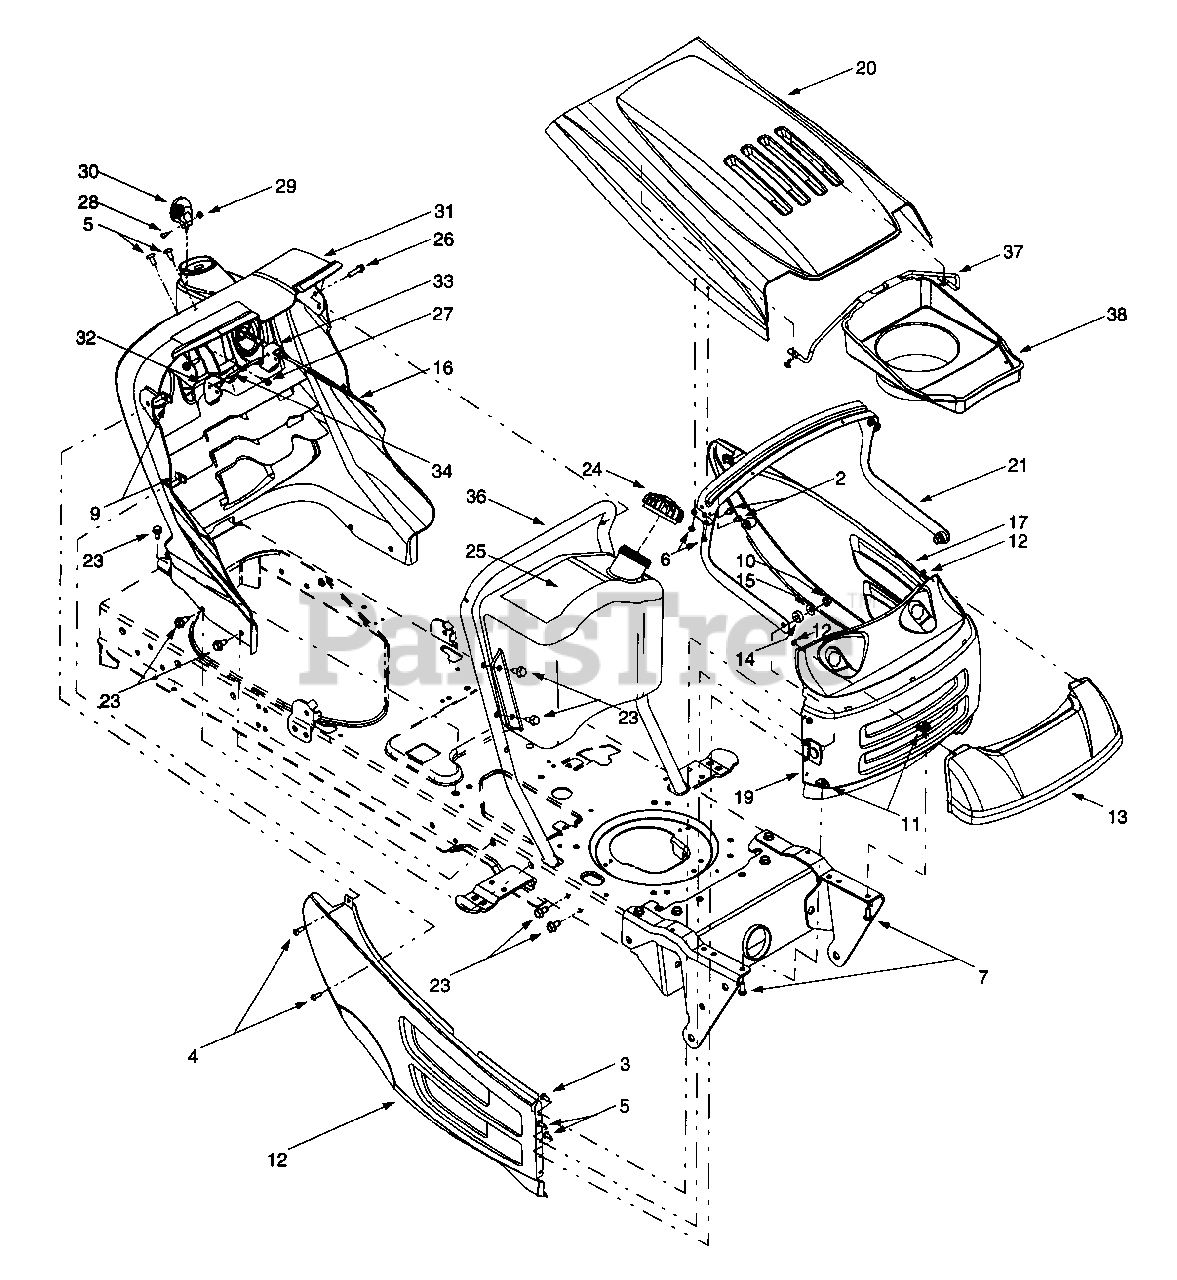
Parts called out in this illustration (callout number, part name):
2	Self-tapping Screw, 1/4-20 x .5
3	Hex Cap Screw, 1/4-20 x .62
4	Phillips Pan Screw, 1/4-20 x .75
5	Truss Phillips Screw, 1/4-20 x .625
6	Screw, #10-16 x .375
7	Hex Cap Screw, 5/16-18 x .75
9	U-type Speed Nut, 1/4-20
10	Flange Lock Nut, 3/8-16
11	U-nut, 5/16-18
12	Retainer Nut, 3/8
13	Headlight Lens, 8-style
14	Rubber Washer, .87 x .33
15	Bell Washer, .401 x .87 x .063
16	Choke Cable/Knob Assembly
24	Fuel Cap
25	Fuel Tank (two gallon)
26	Self-tapping Screw, 1/4-20 x 1
27	Self-tapping Screw, 1/4-15 x .75
28	Truss Phillips Screw, #8-32 x .375
29	Hex Nut, #8-32
30	Throttle Control Knob
31	Dash Panel
32	Cruise Control Button
33	Parking Brake Button
34	Flat Washer, 9/32 x 1/2 x 1/16
38	Heat Shield
